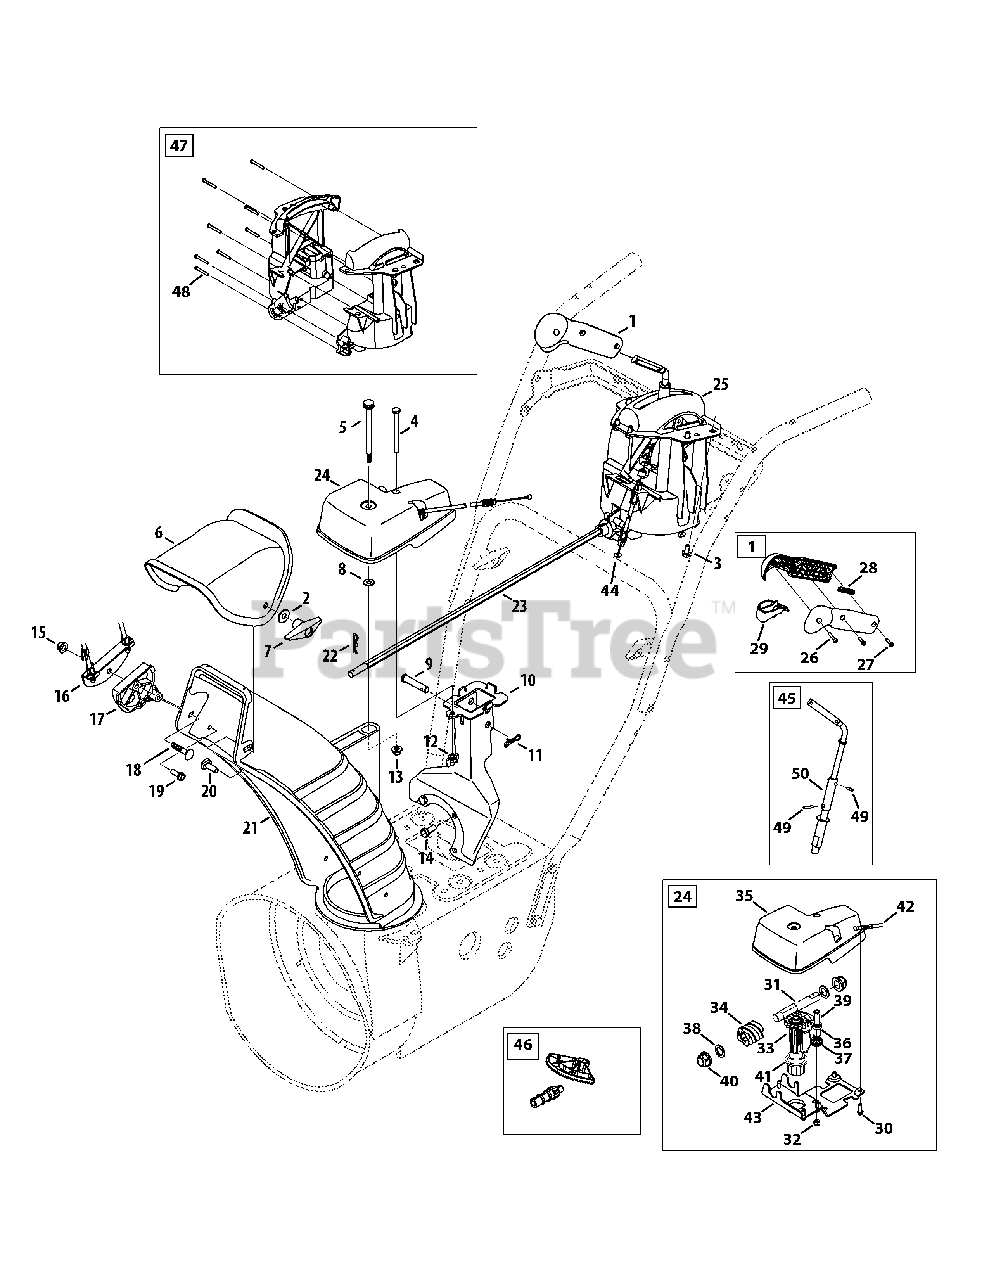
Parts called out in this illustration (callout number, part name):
1	Chute Control Assembly
2	Washer, Flat, .349 x .879
3	Hex Washer Screw, 1/4-15 x .50
4	Hex Head Screw, 1/4-20 x 3.00
5	Screw, Shoulder, .312 x 3.5 x 1/4-20
6	Upper Chute
7	Wing Knob, 5/16-18
8	Washer, Flat, .25 x .630
9	Clevis Pin, 3/8 x 1.87
10	Chute Support Bracket
11	Bow-Tie Cotter Pin
12	Wing Nut, 1/4-20
13	Flange Lock Nut, 1/4-20
14	Hex Lock Screw, 5/16-24 x .750
15	Flange Lock Nut, 5/16-18
17	Chute Tilt Cable Guide
18	Carriage Bolt, 5/16-18 x 1.50
19	Hex Washer Screw, 1/4-15 x .750
20	Carriage Bolt, 5/16-18 x 1.00
21	Lower Chute, 5.0
22	Internal Cotter Pin
23	Chute Rod, 3/8 Hex
24	Gearbox Assembly, Chute Rotation
25	4-Way Chute Control
26	Screw, #8 x 1.00
27	Screw, 8-32 x .750
28	Joystick Plug
29	Joystick Trigger
30	Screw, 12-16 x .75
32	Hexlock Nut, 1/4-28
33	Gear, 14 T
34	Worm
35	Gear Cover
36	Pawl Lock
37	Torsion Spring, .721 ID x .474
38	Washer, Flat, .625 x 1.0 x .067
39	Screw, Shoulder, .340 x .950 x 1/4-28
40	Hex Bearing
41	Flange Bearing
44	4-Way Cable
44	4-Way Cable w/Clip
45	Shift Assembly
46	Gear Set Assembly
47	Handle Housing Assembly
48	Screw, #8-18 x 1.250
50	Block, Asm Joint
